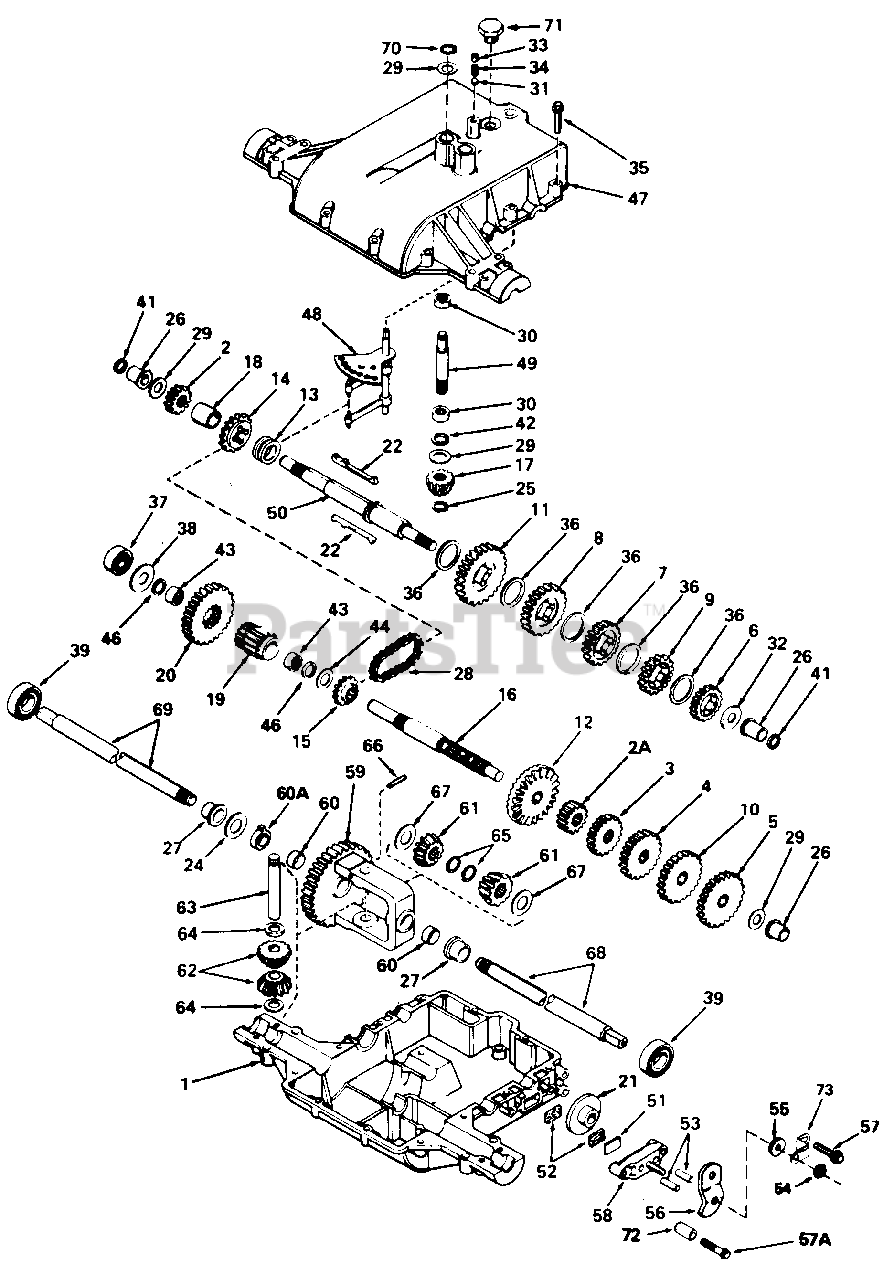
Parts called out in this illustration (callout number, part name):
1	Case, Transaxle
2	Gear, Spur (15 teeth)
2A	Gear, Spur (12 teeth)
3	Gear, Spur (20 teeth)
4	Gear, Spur (2s teeth)
5	Gear, Spur (30 teeth)
6	Gear, Spur (20 teeth)
7	Gear, Spur (25 teeth)
8	Gear, Spur (30 teeth)
9	Gear, Spur (2Z teeth)
10	Gear, Spur (28 teeth)
11	Gear, Spur (37 teeth)
12	Gear, Bevel (42 teeth)
13	Collar, Shift
14	Sprocket (18 teeth)
15	Sprocket (9 teeth)
16	Shaft, Counter
17	Bevel Pinion, Input
18	Spacer
19	Pinion, Output
20	Gear, Output
21	Disk, Brake
22	Key
24	Washer
25	Ring, Retaining
26	Bushing, Flanged
27	Bushing, Flanged
28	Chain, Roller (No. 41 Chain, 24 Links)
29	Washer, Thrust
30	Bearing, Needle
31	Ball, Steel
32	Washer, Thrust
33	Screw, Set, 3/8-16 x 3/8
34	Spring
35	Screw, Hex Hd. Thread Forming, 1/4-20 x 1-1/4"
36	Washer, Thrust
37	Bearing, Ball
38	Washer, Flat
39	Bearing, Ball
41	Ring, Square Cut
42	Ring, Square Cut
43	Bearing, Needle
44	Washer, Flat
46	Ring, Square Cut
47	Cover, Transaxle
48	Rod & Fork Ass'y., Shin
49	Shaft, Input
50	Shaft, Brake
51	Plate, Brake Pad
52	Pad, Brake
53	Pin, Dowel
54	Locknut, 5/16-24
55	Washer, Flat
56	Lever, Brake
57	Screw, Hex Hd. Thread Forming, 1/4-20 x 1-1/4
57A	Screw, Hex Hd. Thread Forming, 1/4-20 x 2-1/4
58	Holder, Brake Pad
59	Gear Ass'y., Differential
60	Bushing
60A	Bushing
61	Gear, Bevel
62	Pinion, Bevel
63	Pin, Drive
64	Washer, Thrust
65	Ring, Retaining
66	Pin, Roll
67	Washer, Thrust
68	Axle (15-1/4" Long)
69	Axle (13-3/8" Long)
70	Ring, Retaining
71	Plug, Hex Hd., 9/16-18 Thread
72	Spacer
73	Bracket, Brake Lever
